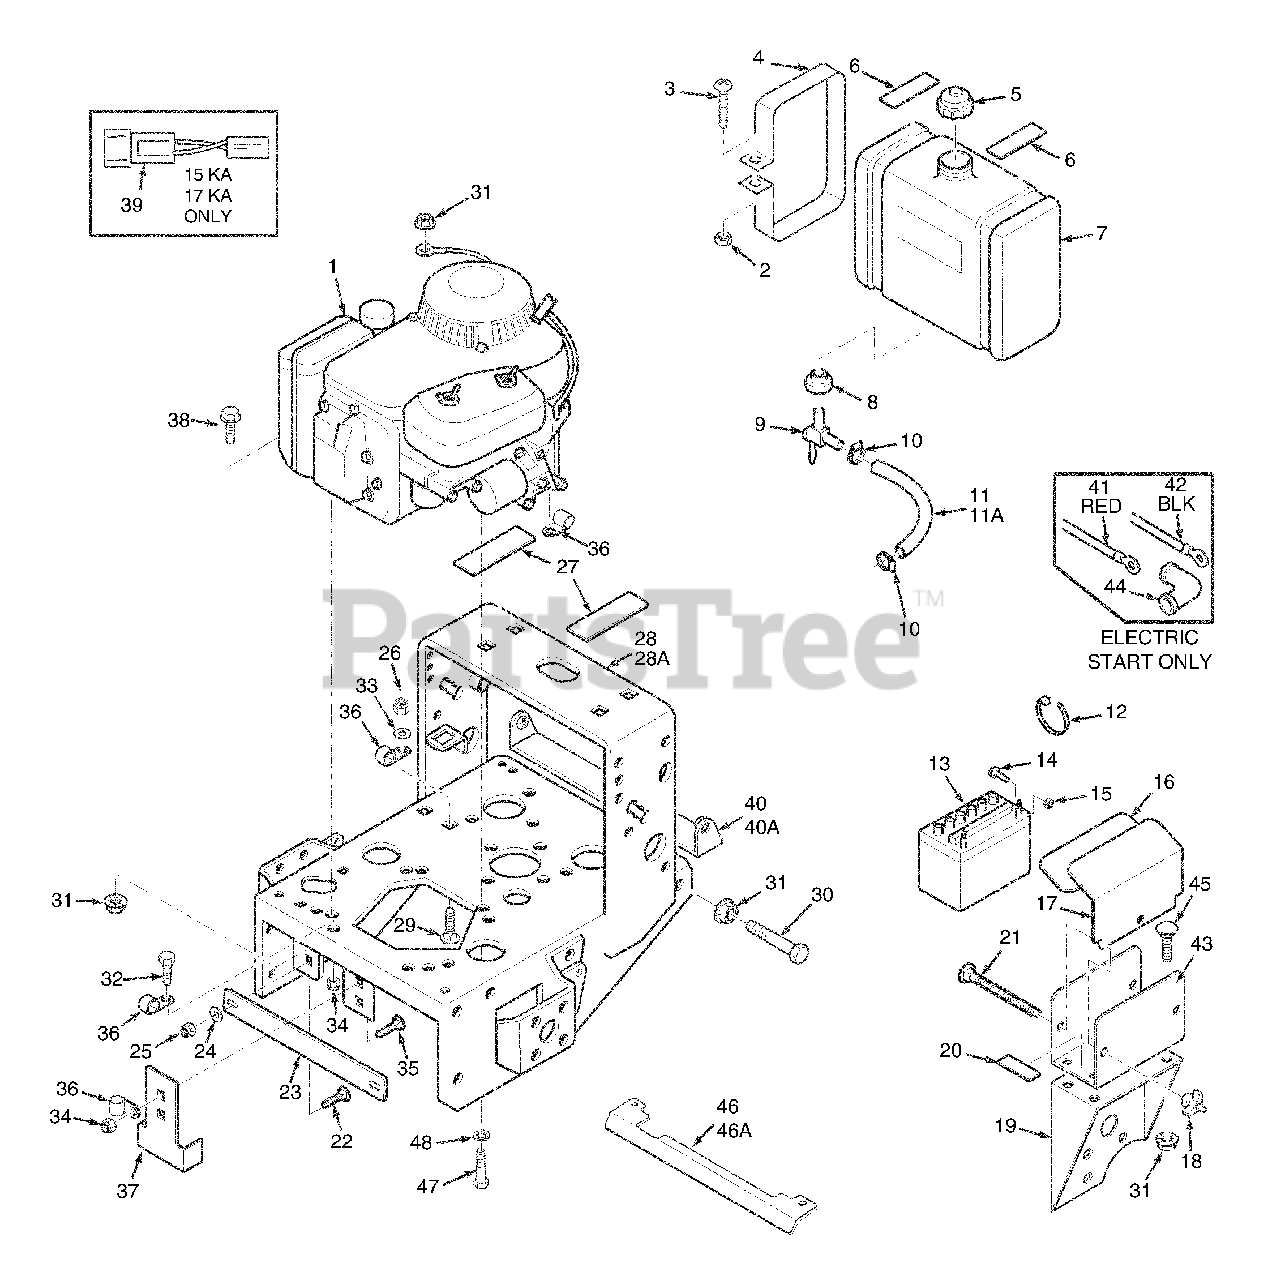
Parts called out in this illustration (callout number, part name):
1	Engine 17KAE Kawasaki
2	Hex Nut, 1/4-20
3	Screw, 1/4-20 x 2" Rnd. Hd. Phil.
4	Strap, Fuel Tank
5	Cap, Fuel Tank
6	Pad, Rubber-Fuel Tank - Upper
7	Fuel Tank Assy.
8	Bushing
9	Valve, Fuel Shut-off
10	Clamp, Fuel Hose
11	Fuel Hose, 1/4 ID x 20" KA
12	Cable Tie
13	Battery
14	Bolt, 1/4-20 x .50"
15	Nut, 1/4-20
17	Battery Cover
18	Wing Nut, 1/4-20
19	Battery Support
20	Pad, Rubber
21	Bolt, 1/4-20 x 6" Carriage
22	Carriage Bolt, 3/8-16 X 1-1/4"
23	Brace
24	Flat Washer .391 x .938 x .105
25	Nut, 3/8-16 Elastic Stop
26	Nut, 1/4-20 Elastic Stop
27	Pad, Rubber-Fuel Tank Lower
28	Engine Deck, 16" Wide, w/decals
29	Bolt, 1/4-20 x 1-1/4" Carriage
30	Bolt, 5/16-18 x 2" Hex Head
31	Nut, 5/16-18 Serr. Flange
32	Hex Head Bolt, 5/16-18 x .75"
33	Flat Washer 1/4"
34	Nut, 5/16-18 Elastic Stop
35	Carriage Bolt, 5/16-18 x 1"
37	Clutch Bracket
38	CapScrw, 5/16-18 x 1.50" Sr. Flg
40	Pulley Guard, 16" Frame
41	Battery Cable, 31.5" Red
42	Battery Cable, 31.5" Black
43	Battery Box
44	Rubber Boot
45	Carriage Bolt, 5/16-18 x .75"
46	Heatshield (16" Small Frame)
